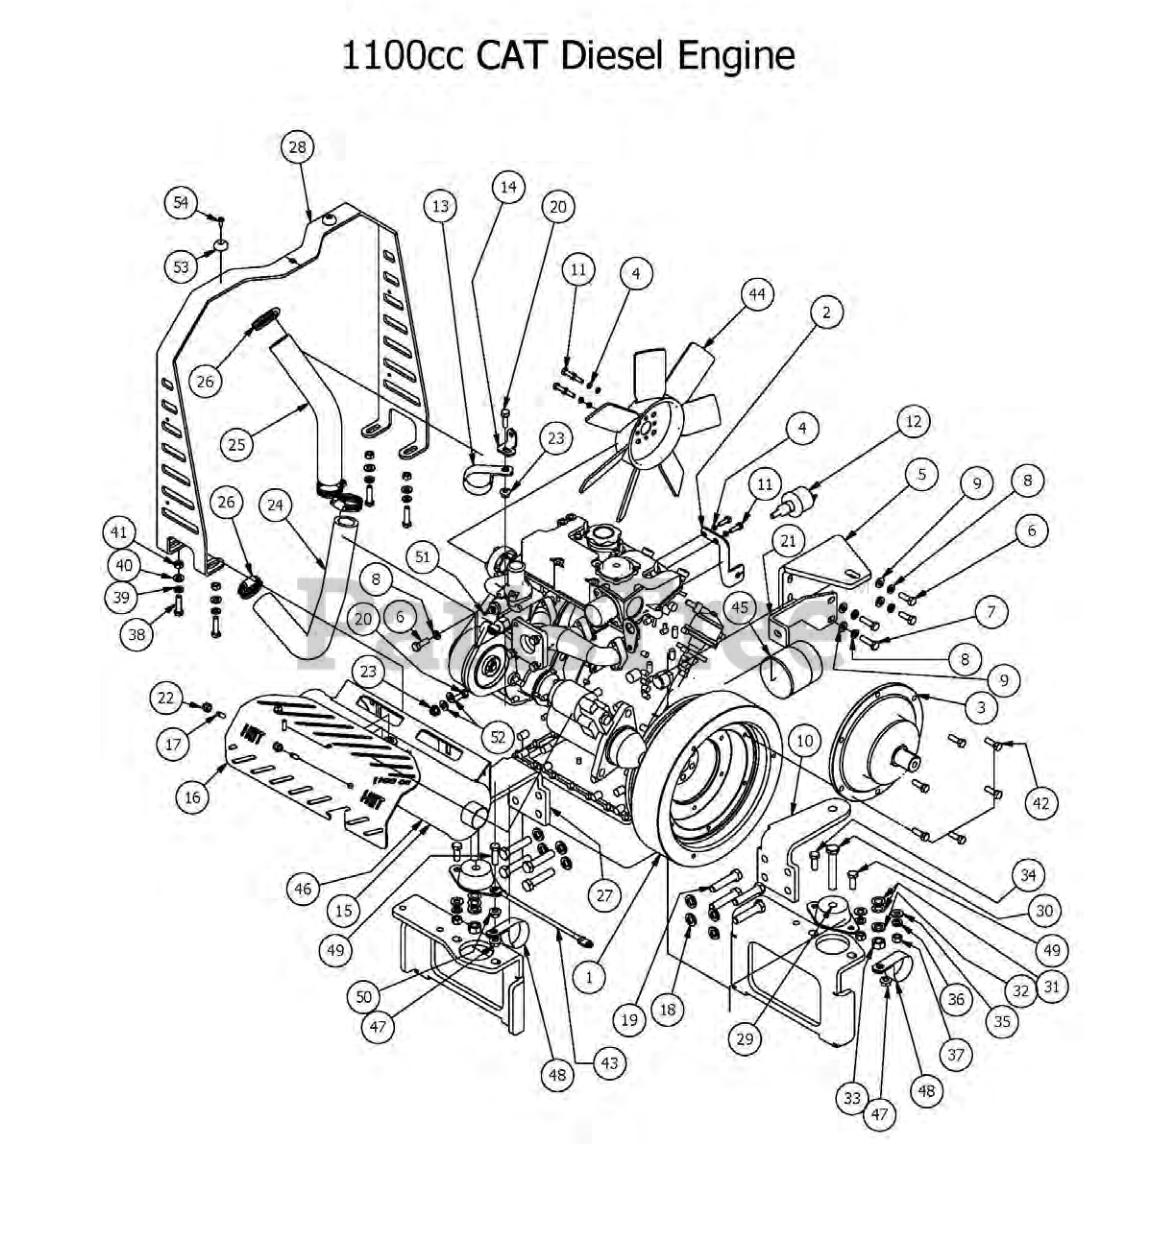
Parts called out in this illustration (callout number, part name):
1	1100cc Cat Diesel Engine
2	Diesel Throttle Bracket (4 Tier)
3	Stub Shaft
4	1/4" Lock Washer
5	Air Cleaner Support Diesel
6	M8 x 1.25 x 25mm Hex Head Bolt
7	M8 x 1,25 x 30mm Hex Head Bolt
8	5/16" Lock Washer
9	5/16" Flat Washer
10	Diesel Motor Side Support Right
11	6mm x 20mm Bolt
12	Pressure Sender-2012 Gauge and Up
13	Diesel Clamp 1 3/4" Vinyl
14	Diesel Radiator Hose Clamp Bracket
15	28/35hp Caterpillar Muffler
16	Diesel Muffler Guard (1100cc)
17	1/4" x 3/4" Set Screw
18	1/2" Lock Was
19	12mm Bolt- Diesel
20	5/16" x 1" Bolt
21	Muffler Brace Diesel
22	1/4-20 Nylon Insert flange Nut
23	5/16" Flange Nut
24	Bottom Radiator Hose for Diesel
25	Top Radiator Hose for Diesel
26	1 1/8" Hose Clamp
27	Diesel Side Motor Mount (Left)
28	Hood Holder Diesel
29	Rubber Isolator
30	1/2" x 3" Hex Bolt
31	1/2" Brass Washer
32	1/2" Lock Washer
33	1/2" Hex Nut
34	3/8" x 1" Hex Bolt
35	3/8" Flat Washer
36	3/8" Lock Washer
37	3/8" Hex Nut
38	5/16" x 1 1/4" Hex Bolt
39	5/16" Lock Washer
40	5/16" Flat Washer
42	5/16-18 x 1 Button Head Bolt
43	Starter to Chassis Cable - Diesel-35 Hp
44	Engine Fan - Diesel
45	CAT Oil Filter
46	Diesel Side Motor Mount Left
47	3/8 Nylock Jam Nut 1/2 Nut
48	Diesel Clamp 1 3/4" Vinyl
49	3/8" x 1 1/2" Hex Bolt
50	3/8" Flange Nut
51	Temperature Sender-2012 Gauge
52	1/4 USS Flat Washer Zinc
53	Button Bumper
54	#10 x 1/2" Self Tapping Screw
